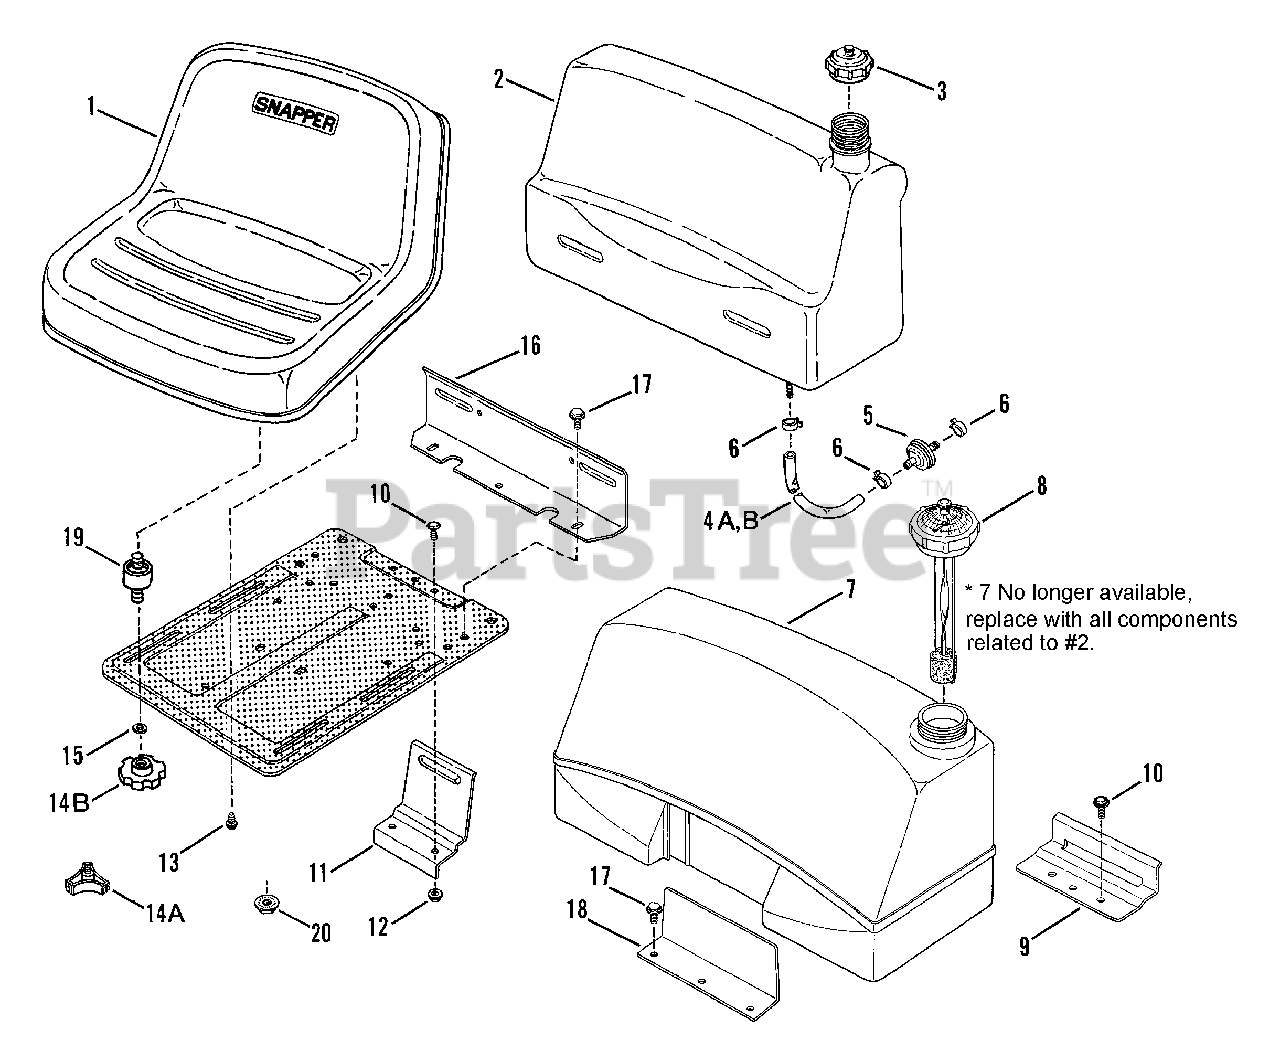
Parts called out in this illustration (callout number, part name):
1	SEAT, Operator
2	ASSEMBLY, Fuel Tank (6.5 & 8 HP Models)
3	CAP, Fuel Tank
4A	HOSE, Fuel, 7" (6.5,8, & 12 HP B&S Engine)
4B	HOSE, Fuel, 12-1/2" (14 HP B&S Engine)
5	FILTER, Fuel, In-Line
6	CLAMP, Fuel Line
7	ASSEMBLY, Fuel Tank (12 & 14 HP Models)
8	CAP & GAUGE, Fuel Tank
9	BRACKET, Fuel Tank, Rear (12 & 14 HP Models)
10	BOLT, 5/16-18x5/8" Short Neck Carriage
11	BRACKET, Fuel Tank, Rear (6.5 & 8 HP Models)
12	NUT, 5/16-18 Hex Flange Lock
13	BOLT, 5/16-18x1/2" Hex Flange Lock
14A	KNOB, Seat Adjusting (8, 12 & 14 HP Models)
14B	KNOB, Seat Adjusting (6.5 HP Models)
15	WASHER, 5/16 Flat
16	BRACKET, Fuel Tank, Front (6.5 & 8 HP Models)
17	SCREW, 5/16-18x5/8" Self-Tapping
18	BRACKET, Fuel Tank, Front (12 & 14 HP Models)
19	MOUNT, ISO Sandwich (6.5 HP Models)
20	NUT, 5/16-18 Hex Flange Lock
